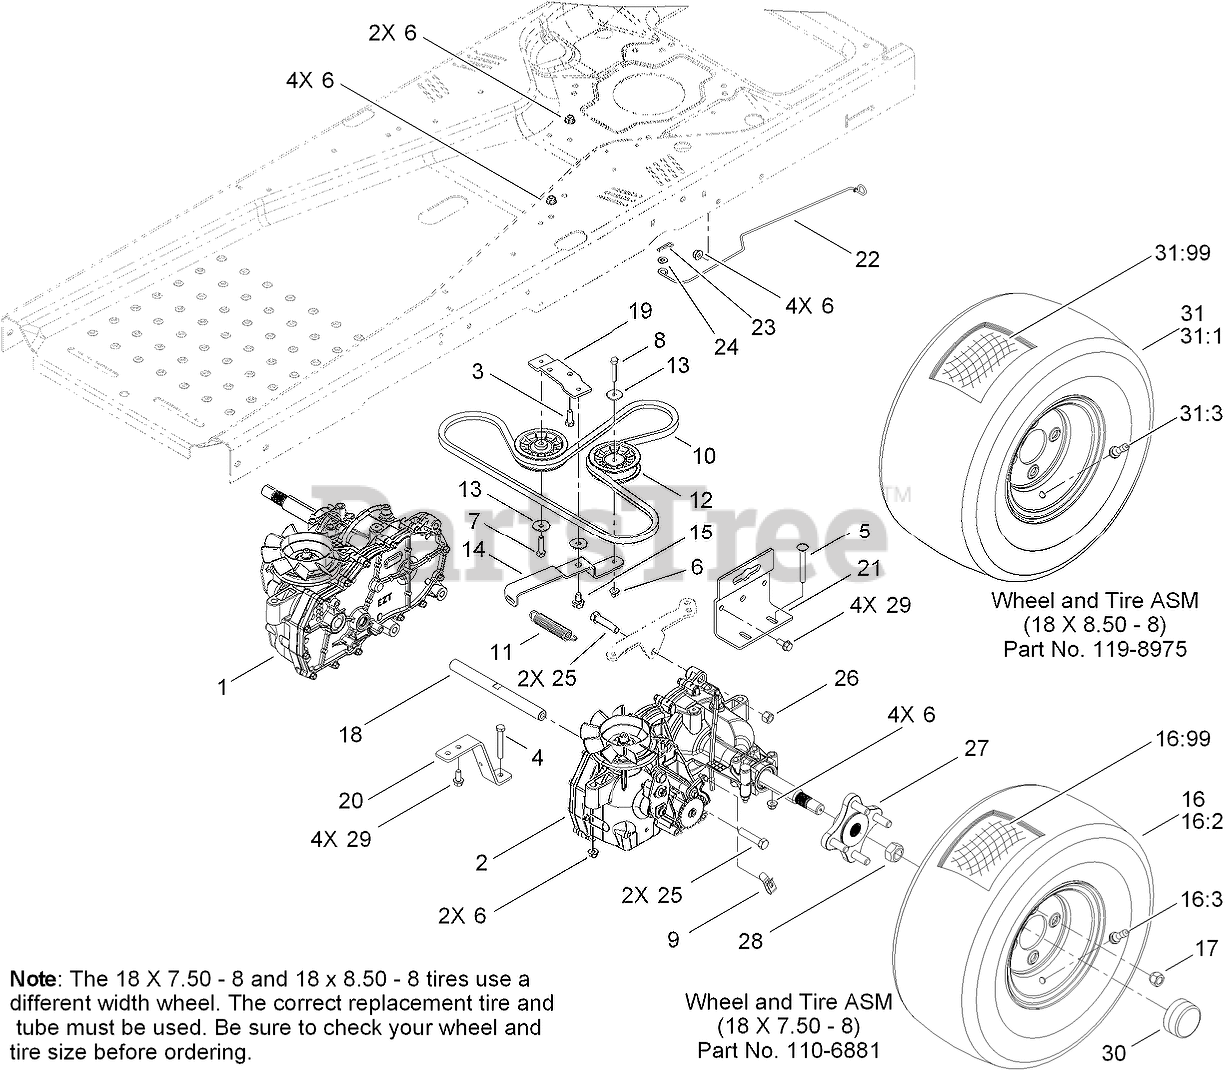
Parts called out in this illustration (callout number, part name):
1	HYDRO-RH
2	HYDRO-LH
3	SCREW-HH
4	SCREW-HH
5	SCREW-CARR
6	NUT-HF, NI
7	SCREW-HH
8	SCREW-HH
9	CLIP-SPRING
10	V-BELT
11	SPRING-IDLER
12	PULLEY-IDLER
13	WASHER-PIVOT
14	ARM-IDLER
15	BOLT-SHOULDER
16	WHEEL AND TIRE ASM
16:2	TIRE
16:3	STEM-VALVE
16:99	TUBE-TIRE
17	NUT-LUG
18	SHAFT-CROSS
19	PLATE-PIVOT
20	STRAP-TORQUE
21	SUPPORT-HYDRO
22	ROD-BYPASS
23	PIN-COTTER
24	WASHER-FLAT
25	SCREW-HH
26	NUT-LOCK, NI
27	HUB ASM
28	NUT-LOCK
29	SCREW-HHF
30	COVER-NUT, AXLE
31	Wheel and Tire ASM
31:1	Tire (18 X 8.50 - 8)
31:3	STEM-VALVE
